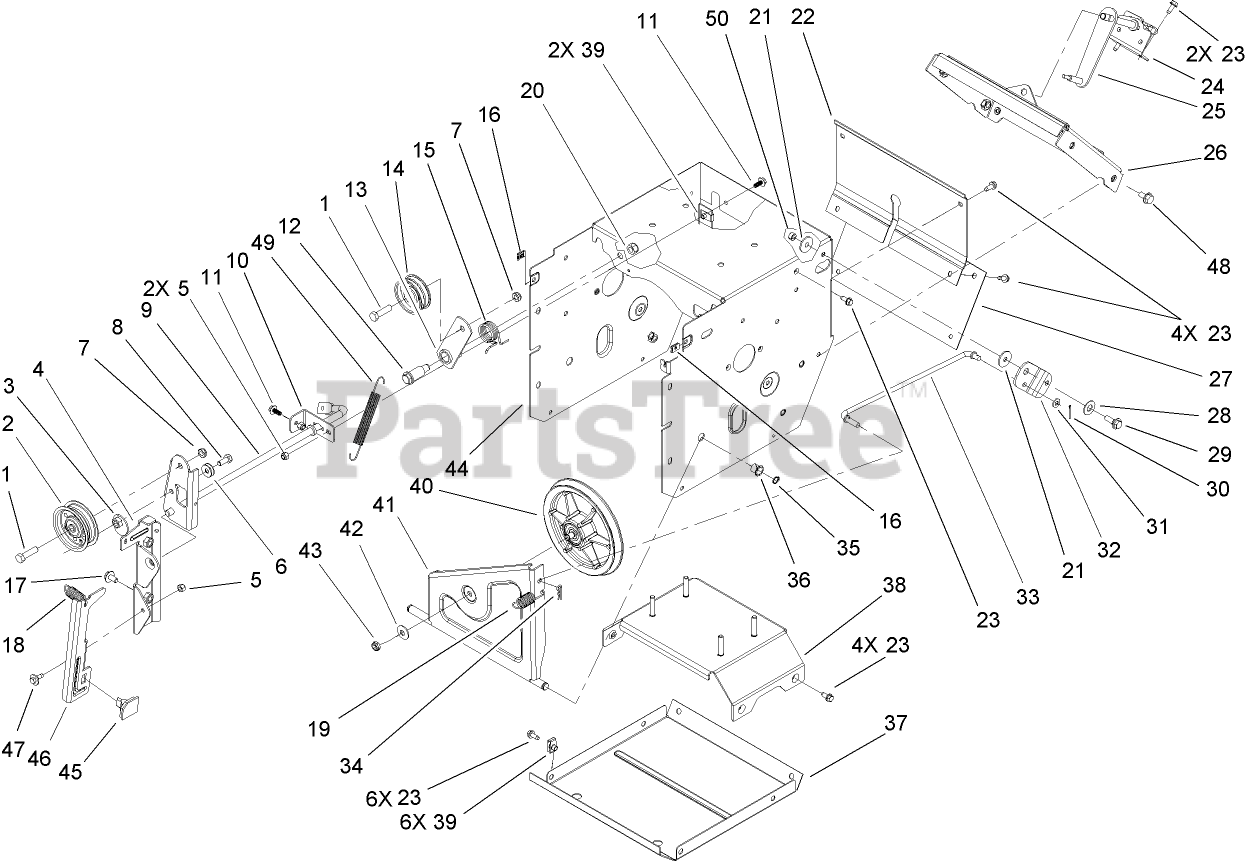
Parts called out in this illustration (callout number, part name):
1	SCREW-HH
2	PULLEY-IDLER
5	NUT-LOCK, NI
6	WASHER-BELLEVILLE
8	SCREW-HH
9	AUGER CLUTCH ASM
10	BRACKET-REAR, CLUTCH
11	SCREW-HHF
12	BOLT-SHOULDER
14	PULLEY-IDLER
16	NUT-SPEED
17	SCREW-HHF
18	SPRING-EXTENSION
19	SPRING-EXTENSION
20	NUT-LOCK, NI
21	WASHER-PIVOT
22	COVER-UPPER
23	SCREW-HWH
25	LEVER-CONTROL, TRACTION
27	COVER-LOWER
28	WASHER
29	SCREW-SHOULDER
30	PIN-COTTER
31	WASHER-PLAIN
32	BELLCRANK-DRIVE
33	LINK-CONTROL, SPEED
35	RING-RETAINING
36	BUSHING-NYLINER
37	PAN-BOTTOM
42	WASHER-BELLEVILLE
43	NUT-HEX
44	FRAME-TRACTION ASM
45	PAD-BRAKE
47	SCREW-SHOULDER
48	SCREW-HWHTF
50	NUT-LOCK, NI
